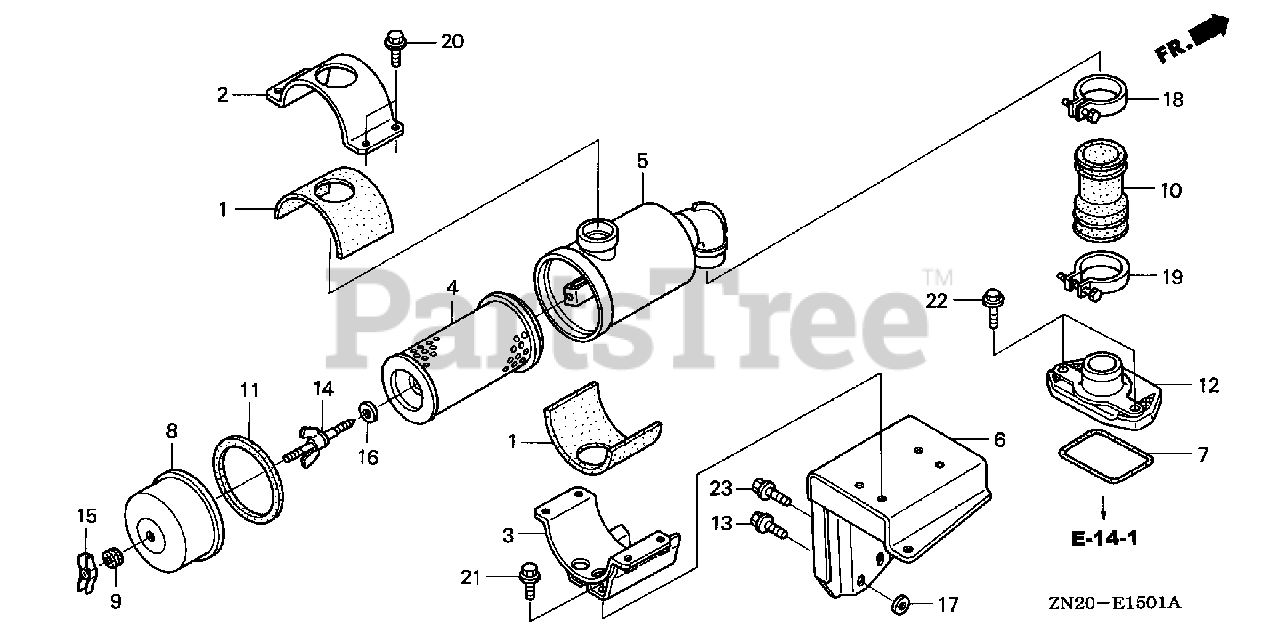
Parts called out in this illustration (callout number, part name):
1	RUBBER, AIR CLEANER HOLDER (UPPER)
2	HOLDER, AIR CLEANER (UPPER)
3	HOLDER, AIR CLEANER (LOWER)
4	ELEMENT, AIR CLEANER
5	HOUSING, AIR CLEANER
6	STAY, AIR CLEANER
7	SEAL, AIR CLEANER HOUSING
8	COVER, AIR CLEANER
9	GROMMET, AIR CLEANER
10	TUBE, AIR CLEANER CONNECTING
11	SEAL, AIR CLEANER
12	JOINT B, CONNECTING TUBE
13	BOLT, FLANGE (6X14)
14	BOLT, AIR CLEANER
15	WINGNUT (6MM)
16	WASHER, AIR CLEANER
17	COLLAR, SEAT
18	BAND, AIR CLEANER CONNECTING TUBE (50)
19	BAND, AIR CLEANER CONNECTING TUBE (58)
20	BOLT, FLANGE (6X12)
21	BOLT, FLANGE (6X16)
22	BOLT, FLANGE (6X28)
23	BOLT, FLANGE (8X16)
